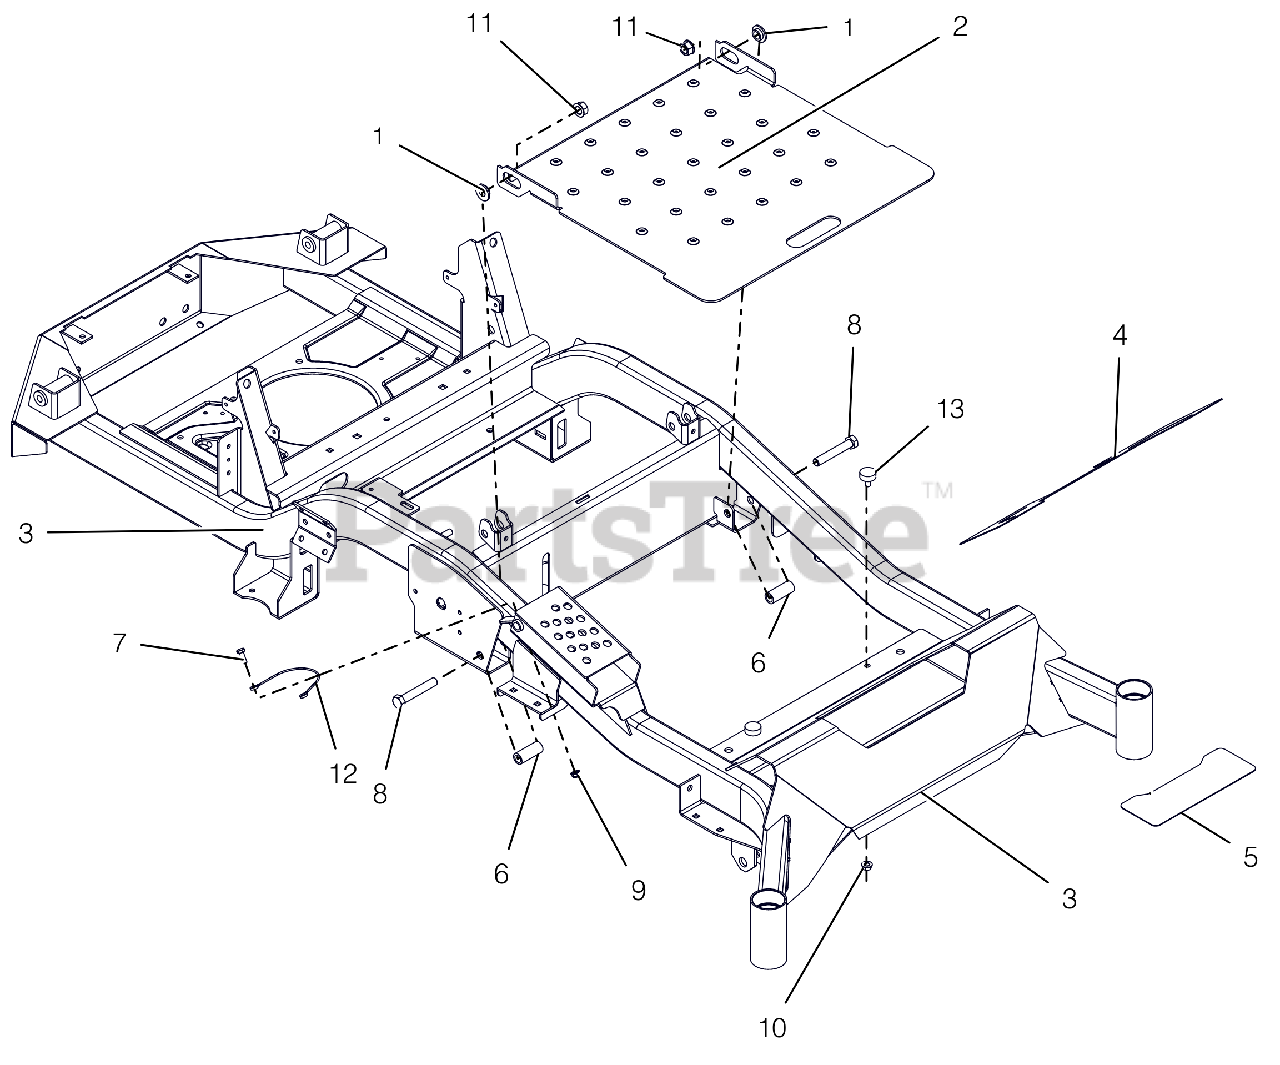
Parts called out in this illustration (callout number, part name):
1	BSHG-FLG .515X.750X.395X1.120
2	PLATE, ACCESS
3	APEX,44-52 FRAME W/SAFETY DECA
4	GRIP, FRONT
5	GRIP, STEP
6	SPACER, .515X.75X1.83
7	@BLT-HEX .25-20X.75 GR5 YWZC
8	@BLT-HEX .50-13X3.00 GR5 YWZC
9	@NUT-LK-NYL-FLG .25-20 YWZC
10	@NUT-SPNLK-FLG .312-18 YWZC
11	@NUT-LK-TOP-FLG .50-13 YWZC
12	CABLE, 12.0 LANYARD, NYLON
13	BUMPER, RUBBER
